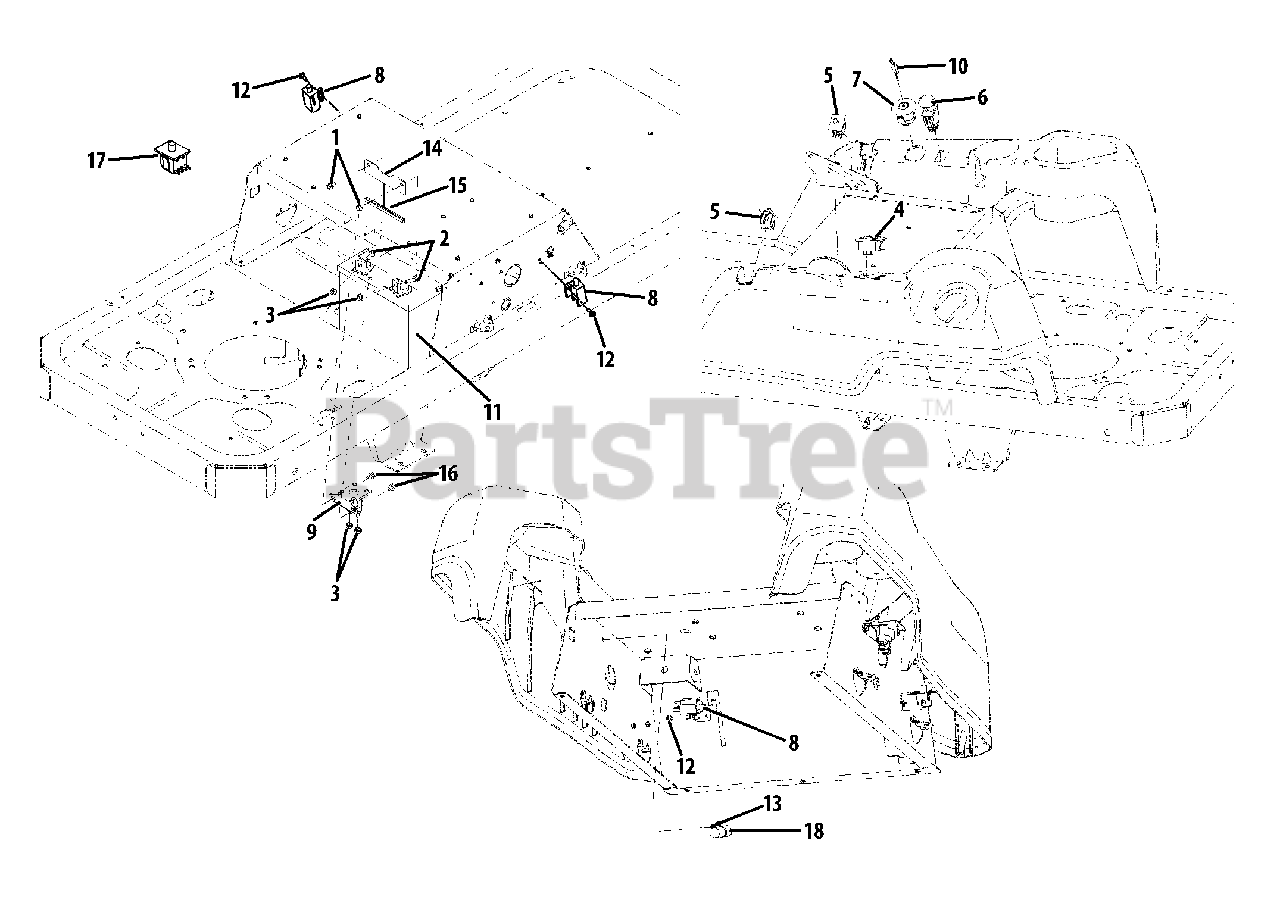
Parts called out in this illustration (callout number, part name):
1	Hex Screw, 1/4-20 x .5
2	Hex Screw, 1/4-20 x .75
3	Hex Nut, 1/4-20
4	Hour Meter
5	Double Pole - Neutral Switch
6	PTO Switch
7	Ignition Switch
8	Interlock Switch
9	Solenoid
10	Key, Assembly
11	Battery, 235 CCA
12	Shoulder Screw, #10-32 x .500
13	Cable Tie
14	Battery Hold-down
15	Trim Strip
16	Hex Screw, 1/4-20 x .375
17	Seat Switch
18	Wire Harness
